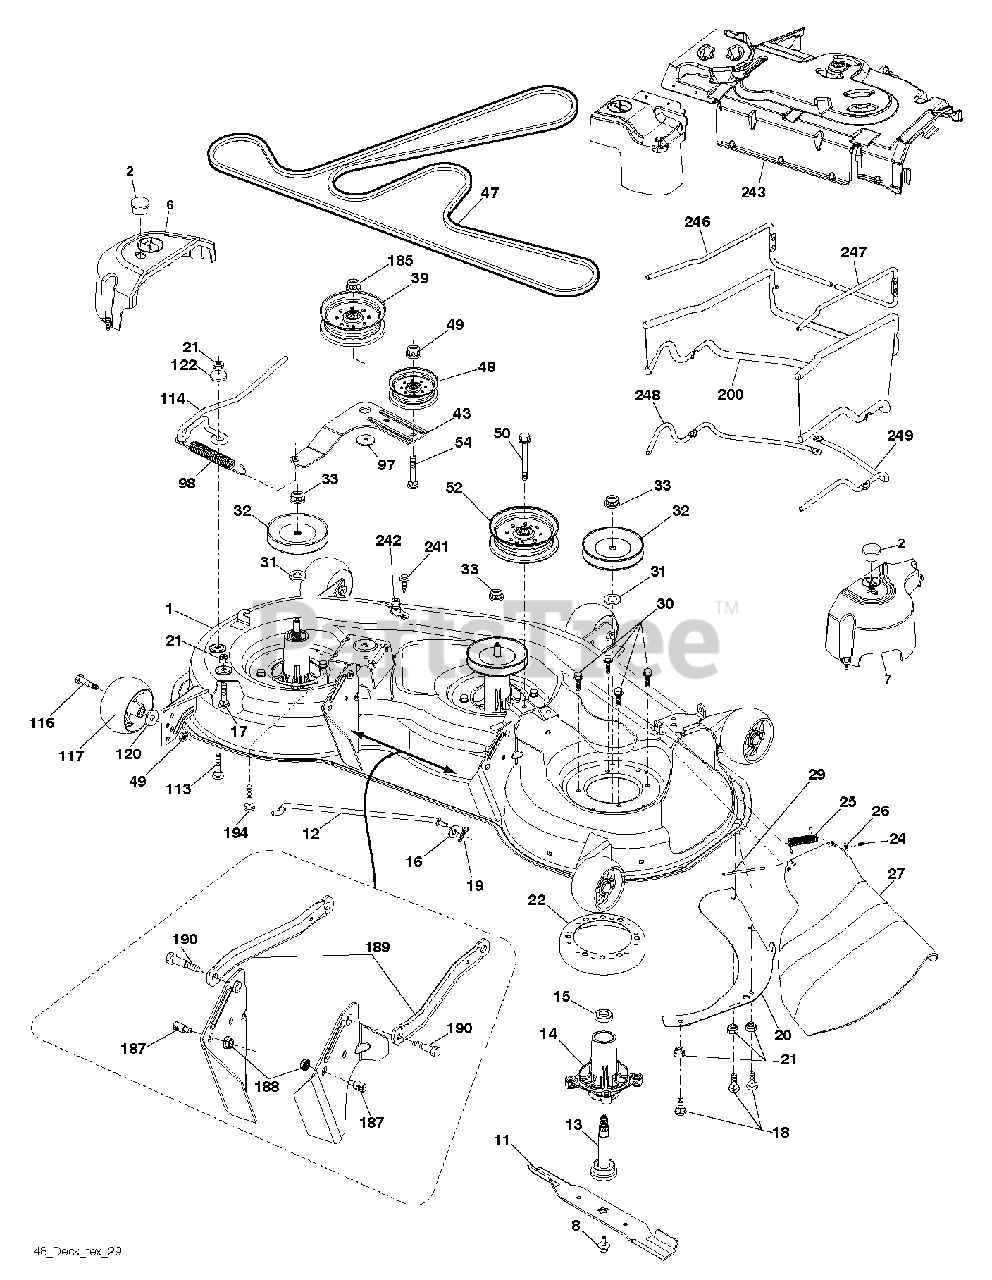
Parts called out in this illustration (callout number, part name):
1	DECK WELDMENT
8	BOLT.WASHER.ASM.7/16-2
11	48" HI-LIFT BLADE
12	ROD.ANTI.SWAY.48/54"K4
13	SHAFT ASM MANDREL
14	HOUSING MANDREL
16	WASHER
17	BOLT
18	BOLT
19	PIN.COTTER.5/16.BOW TI
20	BAFFLE, VORTEX MWR
21	LOCKNUT
22	STRIPPER, MWR ROUND
24	CAP-SLEEVE LT
25	SPRING, TORSION
26	NUT PUSH M
29	ROD.HINGE
30	SCREW, WASHER HEAD
31	WASHER.SPACER.MANDREL
32	PULLEY MANDREL
33	NUT.FLANGE.LOCK.TOP
39	PULLEY.IDLER.4.50/HUB SPECIAL
43	ARM.IDLER
47	BELT.DRIVE.DECK
48	PULLEY.IDLER.48"PRIMARY
49	NUT LOCK FLG 3/8-16 UNC
50	SCREW TT 3/8-16X2-1/4 UNC
52	PULLEY.IDLER.2006
54	BOLT.3/8-16X1.50
98	SPRING, DECK DRIVE
114	ROD.TENSION.RELIEF.TEX
116	BOLT.SHOULDER.3/8-16X3-5/8
117	WHEEL. GUAGE RALLY
122	BUSHING.RELIEF.TENSION
185	NUT.LOCK.FLANGE.7/16
187	STUD.FASTNER.W/ANTI-ROTATE
188	NUT LOCK HEX FLANGE 5/16-18
189	ARM.SUSPENSION.MOWER
190	BOLT.SHOULDER
194	BOLT.HEX.WASHER.HEAD.7/16-24X
242	PORT.WASHOUT
